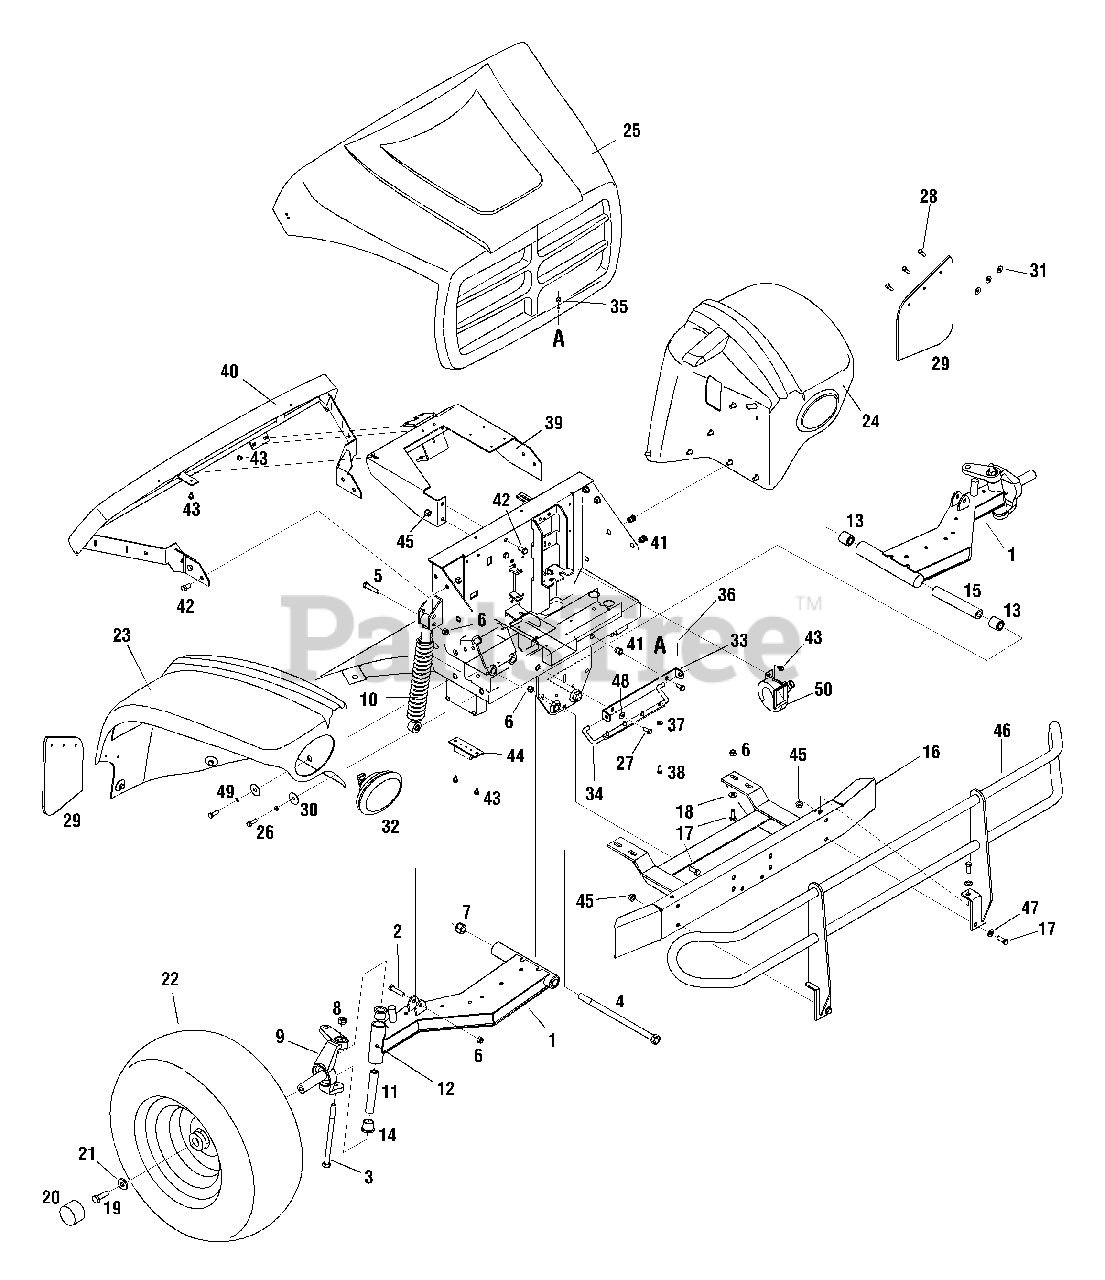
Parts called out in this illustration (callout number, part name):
1	Axle Assembly, Right-front
2	Hex Screw, 3/8-16 x 1.75
3	Hex Screw, 1/2-13 x 7.0, Gr5
4	Hex Screw, 5/8-11 x 11.13, Gr5
5	Hex Screw, 3/8-16 x 2.25
6	Nut, Hex Lock, Nylon, 3/8-16, Gr5
7	Nut, Hex Lock, Nylon, 5/8-11, Gr5
8	Nut, Hex Lock, 1/2-13
9	Steering Control Knuckle, RH
10	Shock Absorber, 2.9 Stroke
11	Tube, .875 x .50 x 4.75
12	Grease Fitting
13	Bearing, .63 ID x 1.19 OD
14	Bushing, Steering
15	Spacer, .645 ID x 1.063 OD
18	Flat Washer,.406 x.875 x.059
19	Hex Screw, 1/2-13 x 1.50, Gr5
21	Flat Washer,.531 x 1.25 x.181
22	Wheel Ass'y, 22 x 11 x 10, RH, All Terr.
23	Panel, Right Fender, Red
24	Panel, Left Fender, Red
25	Panel, Hood, Red
26	Hex Screw 5/16-18 x 1.00 Gr 5
27	Hex Screw, 5/16-18 x.75
28	Pop Rivet
30	Washer, Flat,.350 x 1.25 x.06
31	Flat Washer, .194 x .62 x .063
32	Head lamp Assembly
35	Nut, Hex Lock, 1/4-20
36	Cotter Pin, Internal, 1.42
37	Washer, Flat,.271 x.63 x.065
38	Hex Screw, 1/4-20 x.75
41	Insert Nut, 5/16-18
42	Hex Screw, 3/8-16 x.75
43	Screw, Self-tapping, 1/4-20 x.5
44	Suspension Bumper
45	Flange Lock Nut, 3/8-16
46	Brush Guard
47	Flat Washer,.406ID x.810OD x.051
48	Flat Washer,.344 x.688 x.065
49	Lock Washer, 5/16
50	Horn
